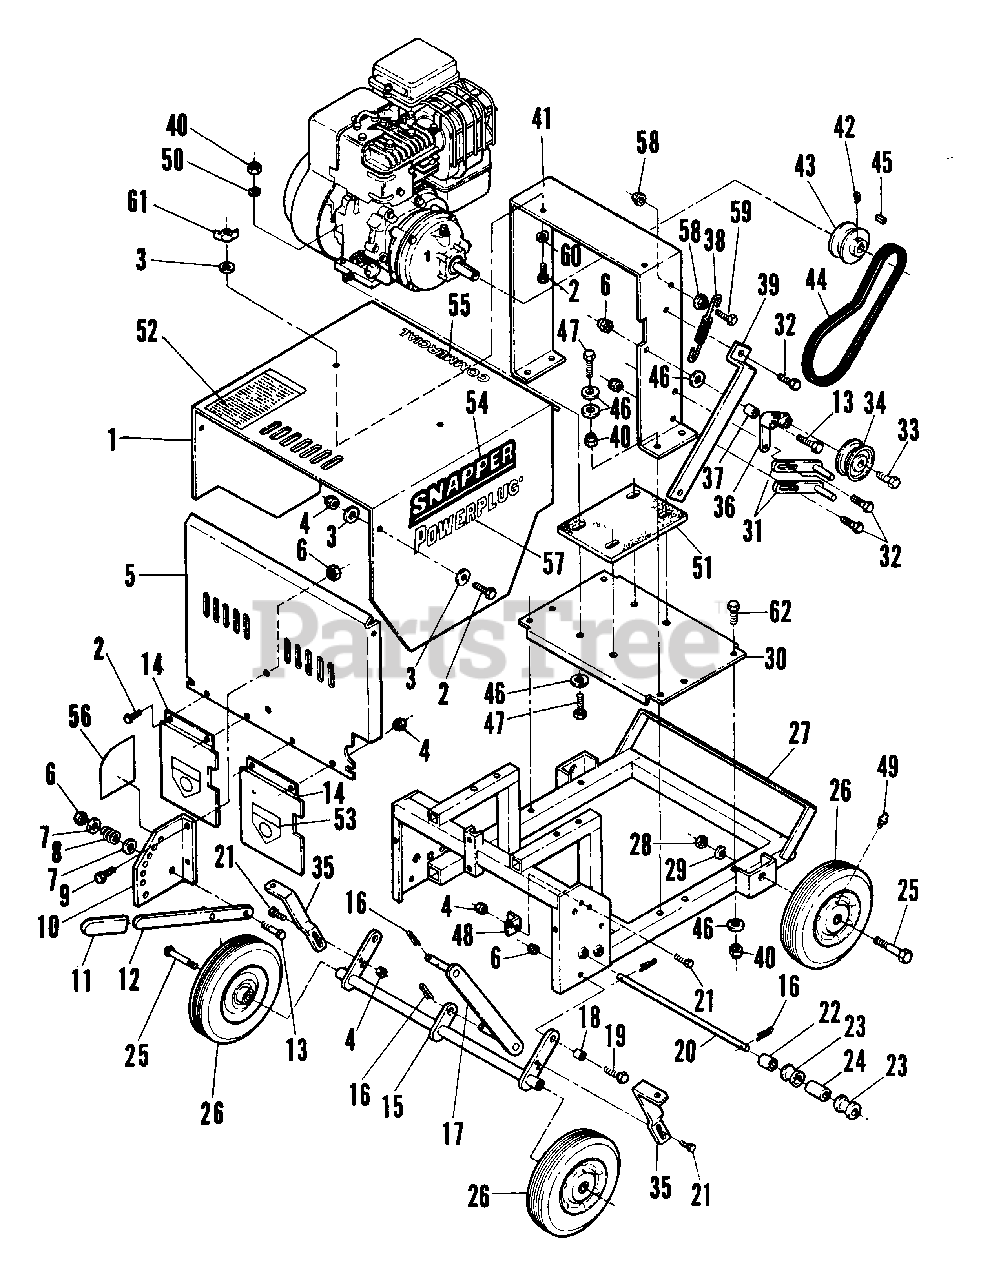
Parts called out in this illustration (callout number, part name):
1	HOOD W/DECALS
2	CAPSCREW, 1/4" - 20 x 5/8" Hex. Hd.
3	FLAT WASHER, 1/4"
4	NYLOC NUT, 1/4" - 20 Hex.
5	REAR GUARD
6	NYLOC NUT, 3/8" - 16 Hex.
7	FLAT WASHER, 3/8" Std.
8	COMPRESSION SPRING
9	CAPSCREW GR. 5, 3/8" - 16 x 1" Hex. Hd.
10	HEIGHT GAUGE W/DECAL
11	GRIP
12	ADJUSTMENT LEVER W/GRIP (76526)
13	CAPSCREW GR. 5, 3/8" - 16 x 2" Hex. Hd.
14	FLAP GUARD W/DECAL
15	REAR AXLE
16	COTTER PIN, 1/8" x 3/4"
17	HEIGHT ADJUSTMENT LINK
18	POWDERED METAL BUSHING
19	CAPSCREW GR.5, 3/8" - 16 x 1 1/4" Hex. Hd.
20	ROLLER ROD
21	CAPSCREW, 1/4" - 20 x 3/4" Hex. Hd.
22	SHORT SPACER
24	LARGE SPACER
25	CAPSCREW,5/8"-11 x 3 1/4" Hex. Hd.
26	10" WHEEL
28	JAM NUT, 5/8" - 11 Hex.
29	LOCK WASHER, 5/8"
30	ENGINE PLATE
31	BELT GUIDE
32	CAPSCREW, 5/16" - 18 x 3/4" Hex. Hd.
33	CAPSCREW GR. 5, 3/8" - 16 x 1 3/4" Hex. Hd.
34	PULLEY, Idler, 3/8" ID, 2.75" OD, 7/8" Wide
35	SCRAPER
36	IDLER ARM
37	POWDERED METAL BUSHING
38	SPRING
40	NYLOC HEX. NUT, 5/16" - 18
41	IDLER MOUNT SHROUD
42	NYLOC SETSCREW, 5/16" - 18 x 3/8"
43	DRIVE PULLEY W/SETSCREW (76956)
44	BELT
45	KEY, 3/16x3/16x1"
46	FLAT WASHER, 5/16"
47	CAPSCREW GR. 5, 5/16" - 18 x 1 3/4"
48	CABLE BRACKET
49	STRAIGHT ZERK, 1/4" - 28
50	LOCKWASHER, 5/16"
51	ENGINE PAD
52	CAUTION DECAL
53	WARNING DECAL
54	SNAPPER DECAL
55	COMMERCIAL DECAL
56	DEPTH ADJ. DECAL
57	POWERPLUG DECAL
58	FLANGE NUT, 5/16" - 18
59	CAPSCREW, 5/16" - 18 x 1 1/2" Hex. Hd.
60	LOCKWASHER, 1/4"
61	NYLON WINGNUT, 1/4" - 20
62	CAPSCREW, 5/16" - 28 x 2 1/4" Hex. Hd.
